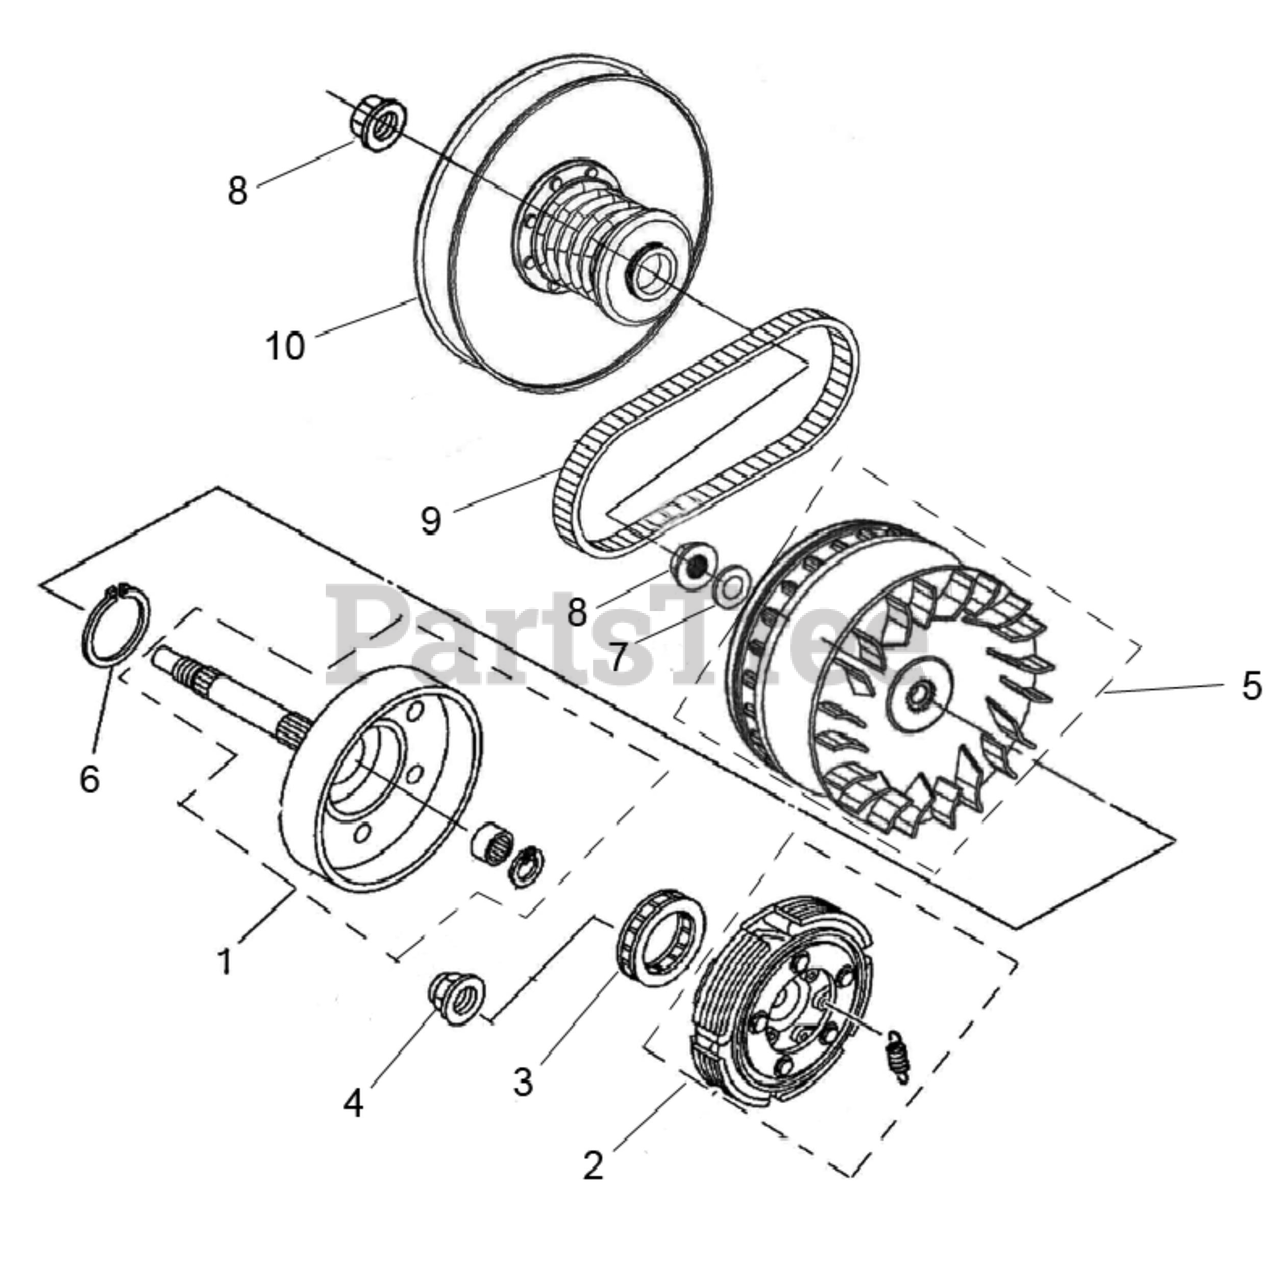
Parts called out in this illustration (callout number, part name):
1	Friction Wheel Assy,Clutch
2	Friction Plate Assy,Clutch
3	Overrunning Clutch Assy
4	Hex Flange Nut M22x1
5	Primary Disc Assy
6	Circlip for shaft 52
7	Washer 19.2x35x3.2
8	Hex Flange Nut M16x1
10	Driven Pulley Assy
